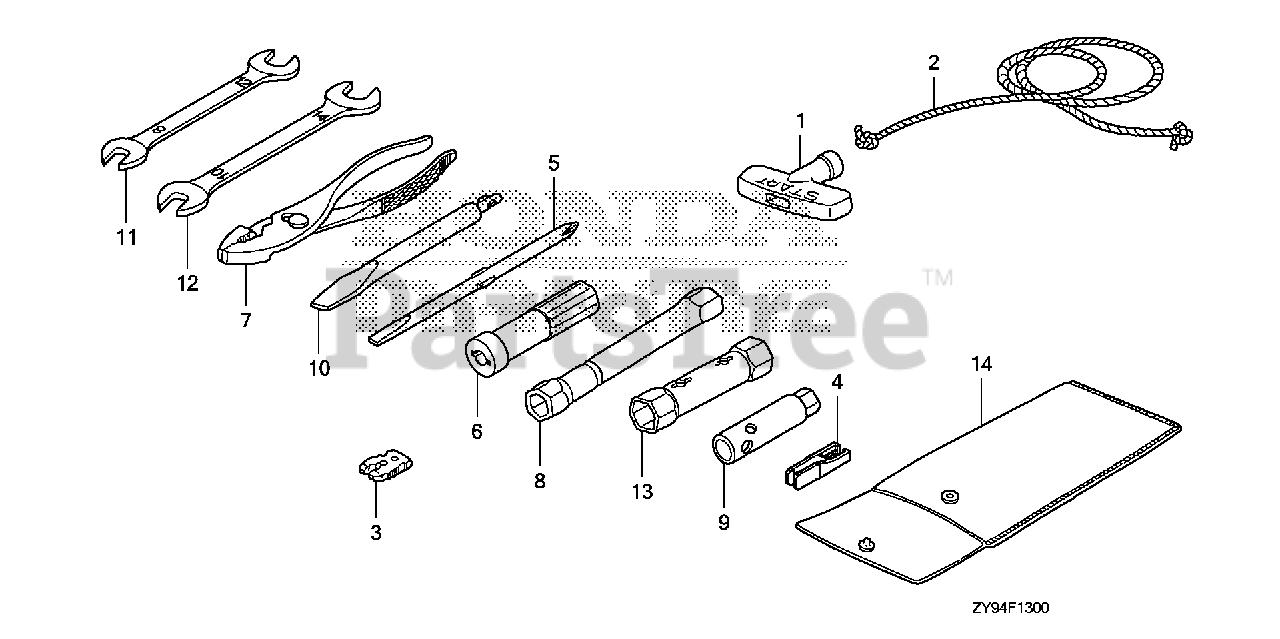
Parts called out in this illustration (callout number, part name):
1	KNOB, RECOIL STARTER
1	GRIP, STARTER
2	ROPE, RECOIL STARTER (1300MM)
3	CLIP, EMERGENCY LOCK
4	PULLER, MINI FUSE (SUMITOMO)
5	SCREWDRIVER (NO.2 PHILLIPS -)
7	PLIERS (135) (RIKEN)
8	WRENCH, PLUG
9	WRENCH, BOX (10MM) (NOT AVAILABLE)
10	SCREWDRIVER, CHECK BOLT
11	WRENCH (8X12) (OPEN END)
12	WRENCH (10X14) (OPEN END)
13	WRENCH, BOX (P18X19)
14	BAG, TOOL
